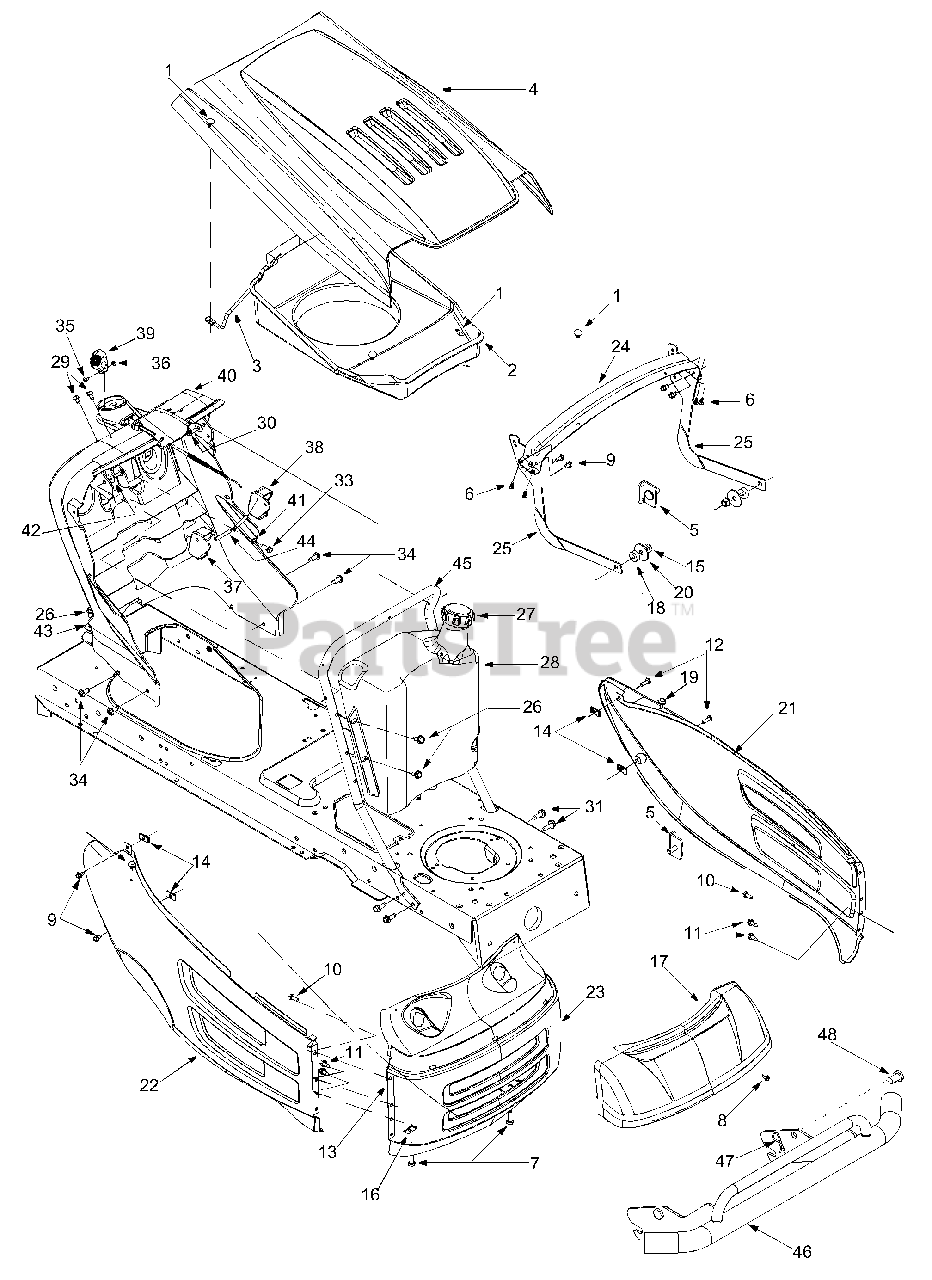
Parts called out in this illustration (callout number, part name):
1	Ratchet Clip
2	Hood Shield
3	Support Rod: Air Duct
6	Pan Head B Screw #10-16 x 0.5
7	Hex Screw 5/16-18 x 1.0
8	Hex Screw #10-16 x 0.5
9	TT Screw 1/4-20 x 0.5
10	Hex Screw 1/4-20 x 0.620
11	AB Screw 1/4-14 x 0.625
12	Machine Screw 1/4-20 x 0.75
13	Sems Nut
14	Nut: Clip
15	Flange Lock Nut
16	U-Nut 5/16-18
17	Lens: 8 Style
18	Rubber Washer
19	Rubber Bumper
20	Flat Washer
27	Fuel Cap
28	Fuel Tank
29	TT Screw 1/4-20 x 0.5
30	TT SCrew 1/4-20 x 0.75
31	TT Screw 5/16-18 x 0.875
33	Hi-lo Screw 1/4-15 x 0.75
34	TT Screw 5/16-18 x 0.75
35	Machine Screw #8-32 x 0.375
36	Nut 8-32
37	Cruise Lever
38	Brake Lever
39	Control Knob
40	Dash Panel
41	Flat Washer
42	Bell Washer
43	Flat Washer
44	Bent Rod: Lever
47	Internal Cotter Pin
48	TT Screw 5/16-18 x 0.75
